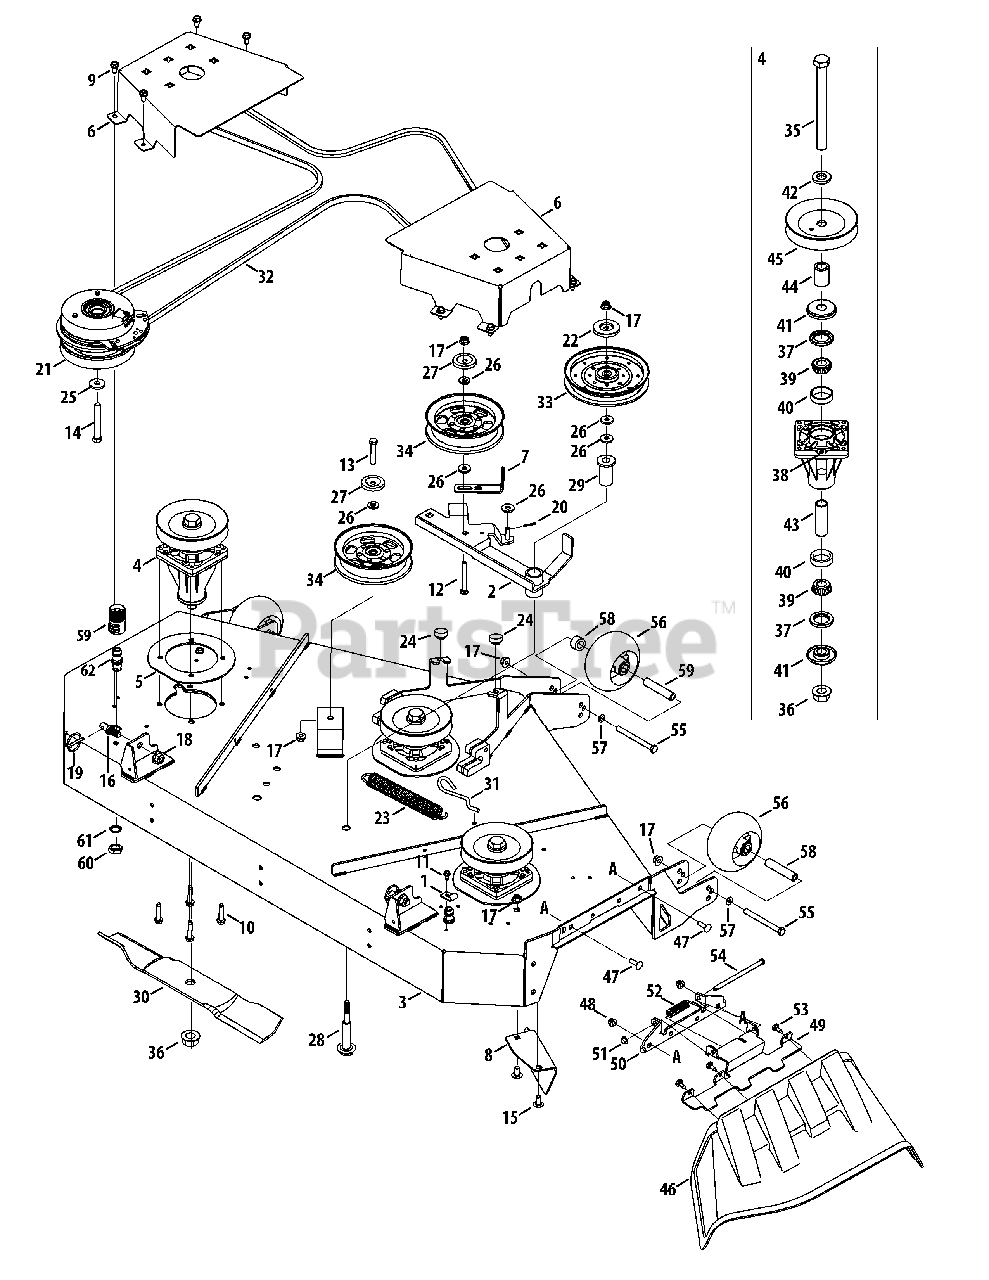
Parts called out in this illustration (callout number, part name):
1	Bracket, Hook Retainer
2	Deck Idler Assembly
3	54" Deck FAB
4	Spindle Assembly
5	Spindle Reinforcement Plate
6	Belt Cover
7	Bracket, Deck Keeper
8	Chute Baffle
9	Hex Washer Screw, 5/16-18 x .750
10	Hex Washer Screw, 5/16-18 x 1.50
11	Hex Washer Screw, 1/4-20 x .500
12	Hex Cap Screw, 3/8-16 x 2.50
13	Hex Cap Screw, 3/8-16 x 2.00
14	Screw, 7/16-20 x 3.25
15	Carriage Screw, 3/8-16 x .75
16	Pin, Shoulder Lock, .500
17	Flange Lock Nut, 3/8-16
18	Flange Lock Nut, 1/2-13
19	Pin, Lynch x .1875
20	Cotter Pin 3/32" Dia. x .75 Lg.
21	Electric PTO Clutch
22	Pulley Cap
23	Extension Spring, 1.25 OD x 1.751
24	Rubber Bumper, 1.00 x .313
25	Flat Washer, .450 x 1.25 x .164
26	Flat Washer, .406 x .875 x .105
27	Pulley Cap
28	Shoulder Boult, .625 x 2.12, 3/8-16
29	Shoulder Spacer, 1.055 x .627 x 2.292
30	Blade, 19.00
31	Deck Spring Rod
33	Idler Pulley, 6.00 Dia
34	Idler Pulley, 5.00 Dia.
35	Hex Cap Screw, 3/4-16 x 8.25
36	Nut, 3/4-16, Flangelock
38	Grease Fitting
39	Cone Bearing
40	Cup Bearing
41	Spindle Spacer
42	Spacer, .812 ID x .218 LG
43	Spacer, .78 x 1.00 x 2.895
44	Spacer, .792 x 1.20 x 1.628
45	V-Type Pulley
46	Discharge Chute Assembly
47	Carriage Bolt, 5/16-18 x 1.00
48	Flange Lock Nut, 5/16-18
49	Chute Bracket
51	Push Cap
52	Torsion Spring
53	Shoulder Screw, 1/4-20
54	Chute Rod
55	Hex Cap Screw, 3/8-16 x 4.0
56	Deck Ball Wheel, 5.0
57	Flat Washer, .406 x .875 x .059
58	Wheel Spacer
59	Water Nozzle Adapter
60	Hex Nut, M-16 x 1.5
61	Lock Washer, 17 x 23.8 x 1.95
62	Deck Water Nozzle
